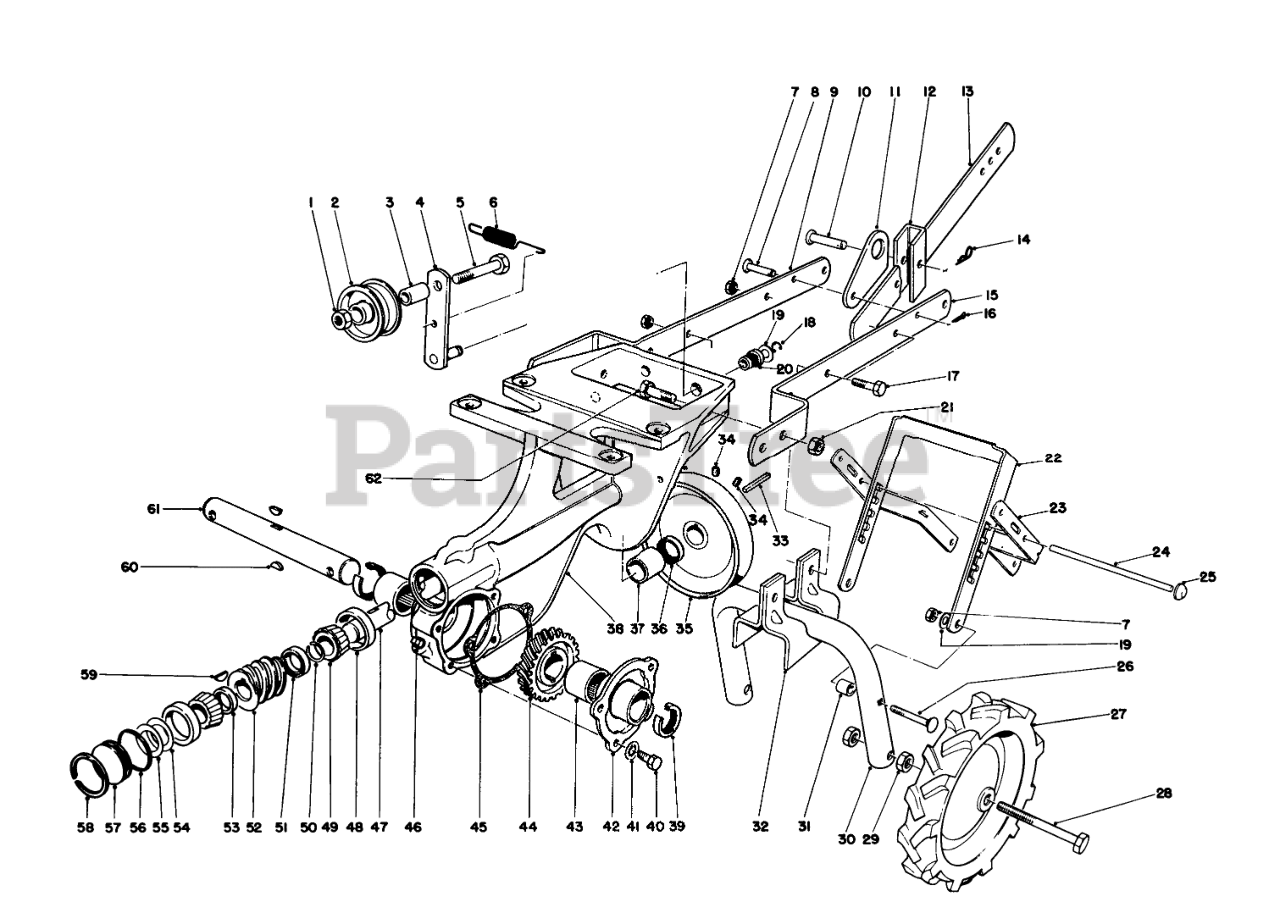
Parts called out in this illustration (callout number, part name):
1	NUT-LOCK, CONE
2	PULLEY IDLER
3	Spacer
4	Idler Arm
5	SCREW-HH
6	TENSION SPRING
7	NUT-LOCK, CONE
8	PIN-CLEVIS
9	Drawbar R.H.
10	CLEVIS
11	Latch-Depth Gauge
12	DEPTH GUAGE BRKT
13	Depth Gauge
14	PIN-COTTER, HAIR
15	Drawbar L.H.
16	PIN-COTTER
17	SCREW-HH
18	RING-RETAINING, EXT
19	WASHER-PLAIN
20	IDLER BRG
21	NUT-KEPS
22	Lever Wheel Adjustment
23	HANDLE SUPPORT
24	Shaft-Wheel Adjustment
25	PUSH ON
26	BOLT-CARR
27	Wheel
28	Wheel Bolt
29	NUT-HEX
30	Axle Yoke
31	Spacer
32	Saddle Yoke
33	KEY-SQUARE
34	SCREW-SET
35	Pulley-Oil Seal
36	SEAL-OIL
37	BUSHING
38	Chassis
39	SEAL-OIL
40	1/4-20 X 5/8 CAPSCREW
41	WASHER-LOCK
42	Cover
43	Needle Bearing
44	WORM WHEEL
45	GASKET
46	PLUG-PIPE, SQH
47	WORM SHAFT
48	Bearing Cup
49	BEARING-CONE
50	RETAINER RING
51	Spacer Rear
52	WORM GEAR
53	SPACER
56	O-RING
58	INTRNL RETAINING RING
59	KEY-WOODRUFF
60	KEY-WOODRUFF
61	WORM WHEEL SHAFT
62	SCREW-HH
